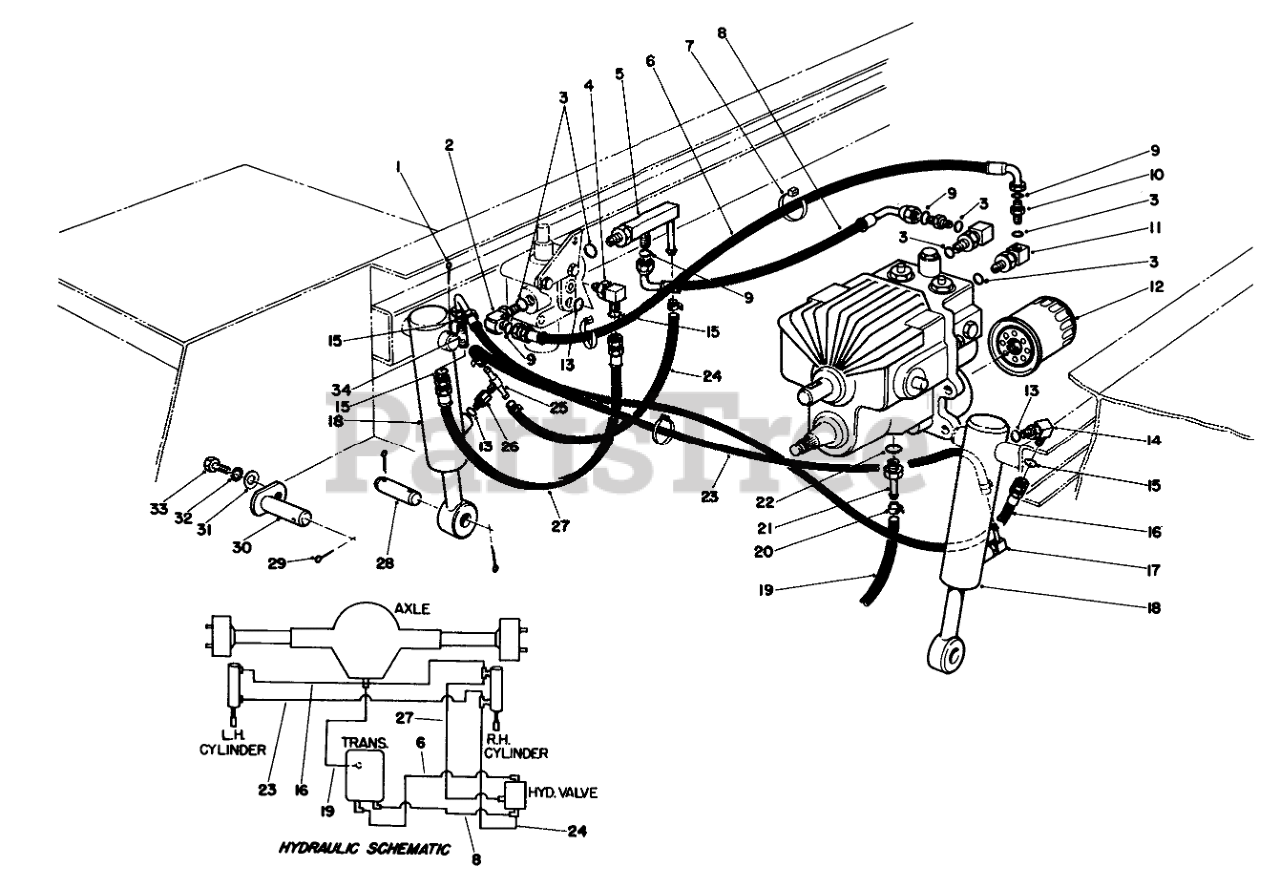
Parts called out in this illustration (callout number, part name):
1	PIN-COTTER
2	FITTING-ELBOW-90
3	O-RING
4	FITTING-90 DEG
5	FITTING ASM
6	HOSE ASSEMBLY
7	TIE-CABLE
8	HYDRAULIC HOSE ASM
9	O-RING
10	FITTING-STRAIGHT
11	FITTING-HYD, 90 DEG
12	FILTER-OIL, TRANSMISSION
13	O-RING
14	90 DEGREE ELBOW
15	O RING
16	HOSE ASSEMBLY
17	STEM-HOSE
18	Cylinder-Hydraulic
19	HYDRAULIC HOSE
20	CLAMP-HOSE
21	Fitting (Incl. Ref. #21)
22	O-RING
23	HOSE-FUEL
24	HYDRAULIC HOSE
25	MALE TEE FITTING
26	CONN FITTING
27	HOSE ASSEMBLY
28	PIN-CYLINDER
29	PIN-COTTER
30	Pin-Pivot
31	WASHER-FLAT
32	WASHER-LOCK
33	SCREW-HH
34	FITTING-TEE
